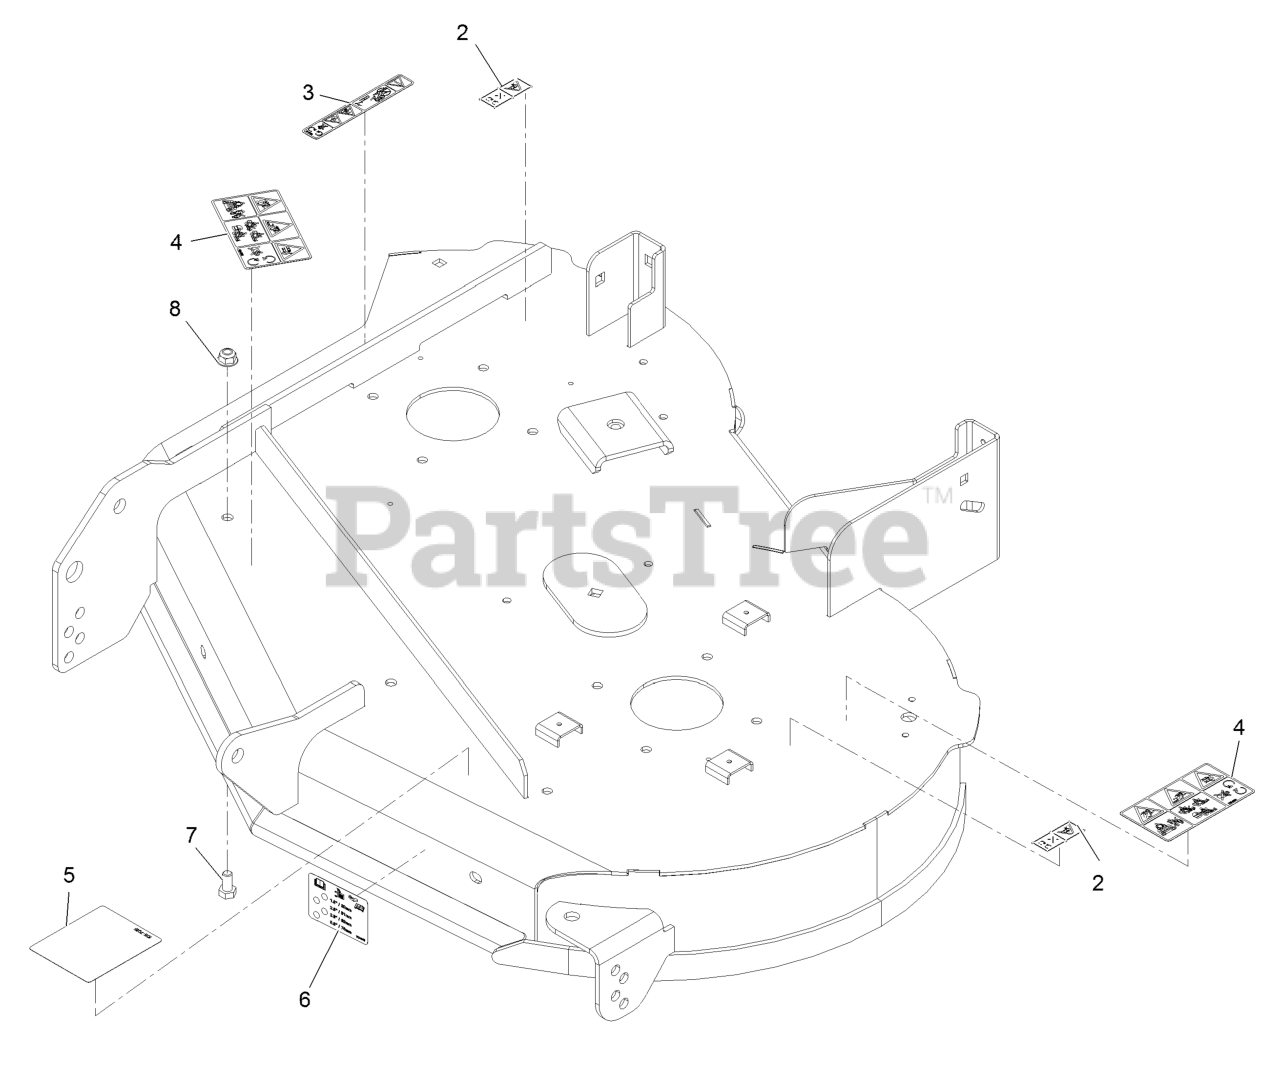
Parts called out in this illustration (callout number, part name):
2	DECAL-DANGER
3	DECAL-DANGER
4	DECAL-DANGER
5	DECAL-ROUTING, BELT
6	DECAL-SCALP, ANTI
7	SCREW-HH
8	NUT-HF, NI
